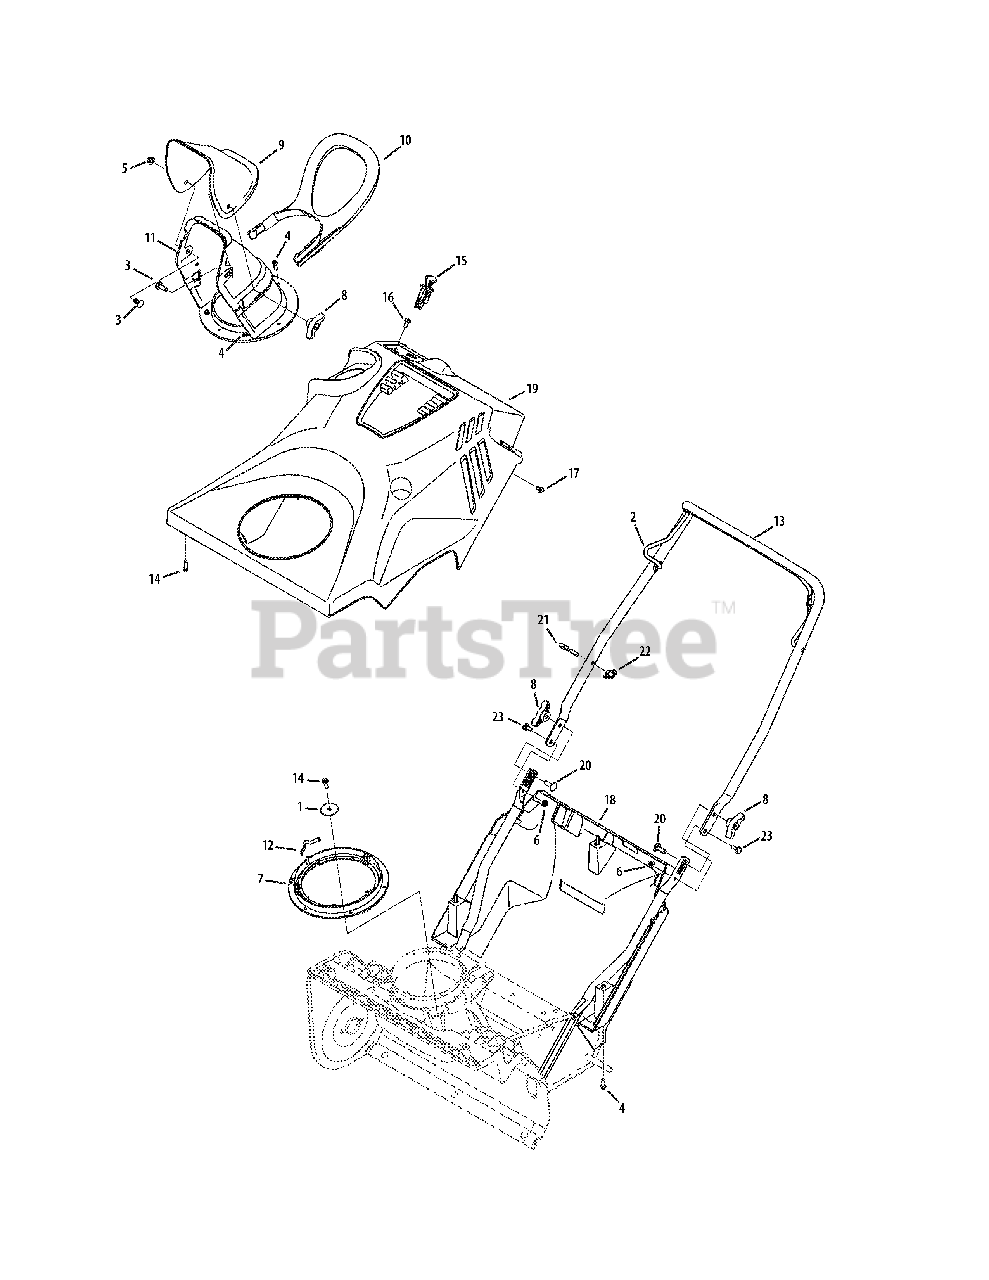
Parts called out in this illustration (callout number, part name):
1	Flat Washer, .28 x 1.5 x .075
3	Carriage Bolt, 5/16-18 x .750
4	Hex Washer Screw, 1/4 x .750
5	Flange Lock Nut, 5/16-18
6	Flange Lock Nut, 1/4-20
7	Chute Ring
8	Wing Knob, 5/16-18
9	Upper Chute
10	Chute Handle
11	Lower Chute
12	Chute Adjustment Spring
13	Upper Handle
14	Screw, Hi-Lo:1/4-15, 0.75
15	Ignition Switch Assembly
16	Hex Washer Screw, 1/4-15 x .50
17	Hex Washer Screw, 1/4-20 x .625
18	Bottom Cover
19	Top Cover (1X 21")
20	Carriage Screw, 5/16-18 x 1.00
21	Eye Bolt, 1/4-20
22	Handle Knob
23	Shoulder Screw, 1/4-20 x .375 x .148
